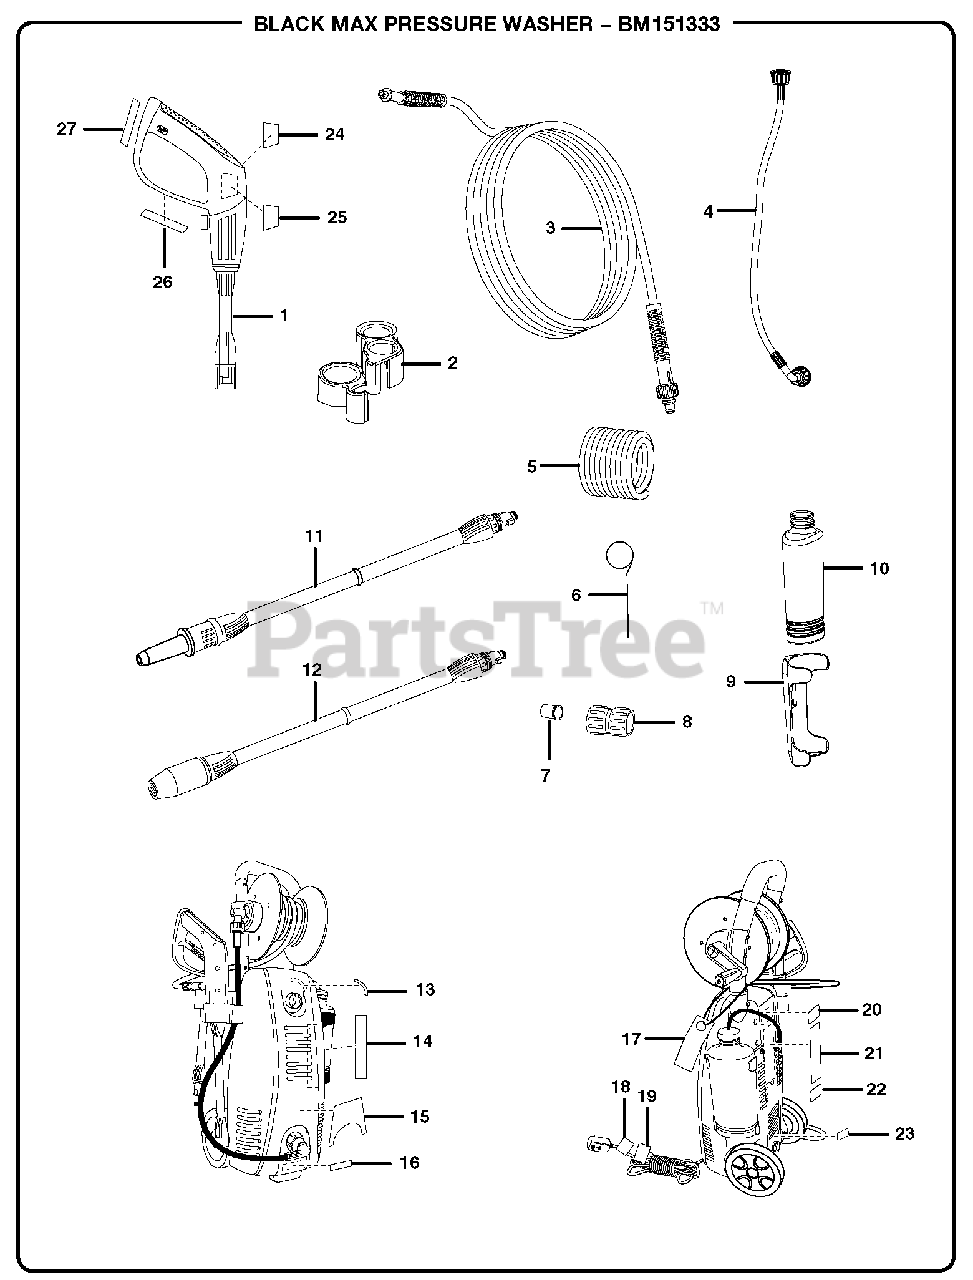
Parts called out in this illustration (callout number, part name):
1	Trigger Handle
2	Wand and Trigger Storage Bracket
3	High Pressure Hose
4	High Pressure Extension Hose
5	High Pressure Hose (for Hose Reel)
6	Nozzle Cleaning Tool
7	Water Inlet Filter
8	Garden Hose Coupler
9	Detergent Tank Holder
10	Detergent Tank
11	Turbo Spray Wand
12	Variable Fan Spray Wand
13	On/Off Label
14	Quick Start Label
15	Logo Label
16	Hose Outlet Label
18	CA Proposition 65 Label
19	Danger cordwrap
20	Carry Handle Label
21	Danger Label
22	Data Label
23	Hose Inlet Label
24	Trigger Handle Logo Label
25	Trigger Handle Warning Label
26	Trigger Handle Spec Label
27	Trigger Handle Warning Label
